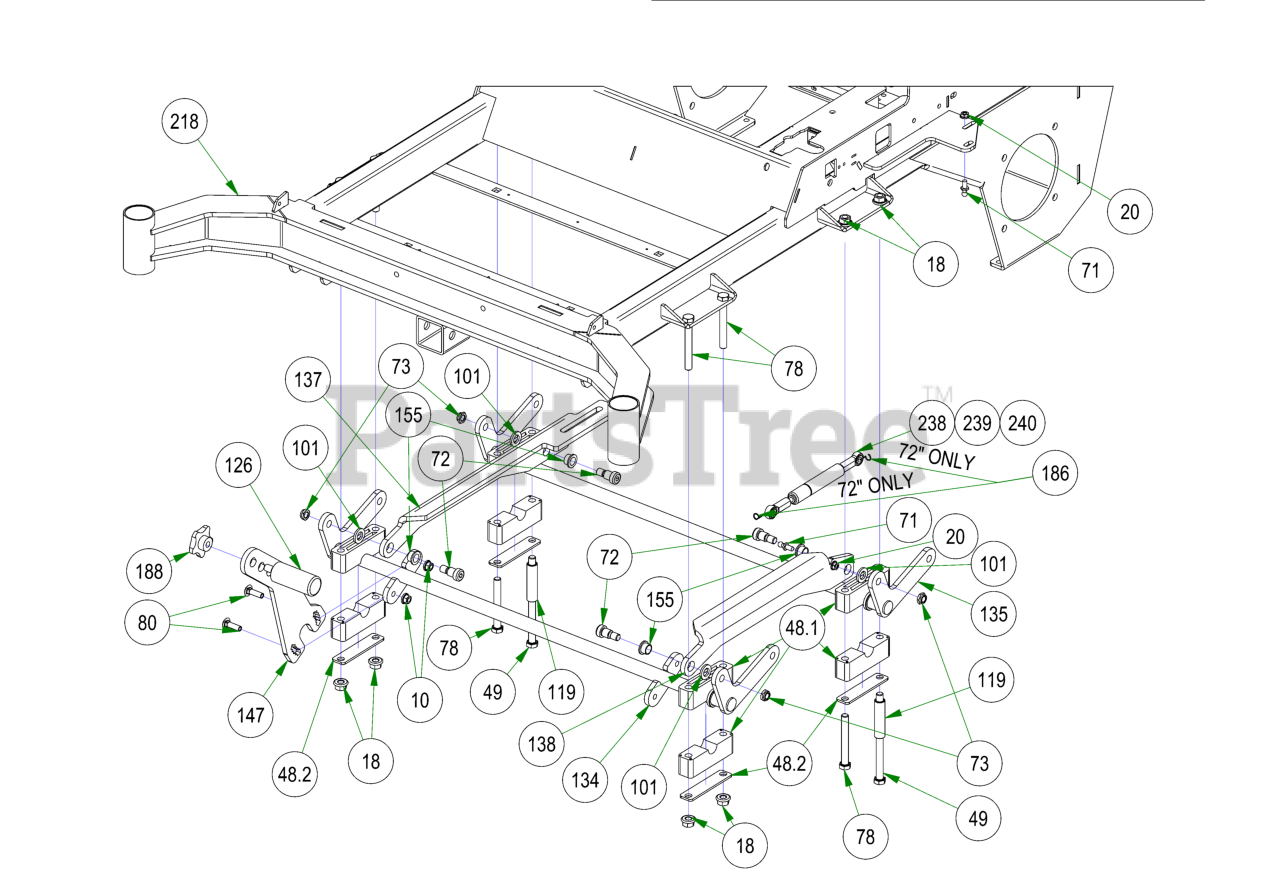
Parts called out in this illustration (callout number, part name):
5	.625 ID x 1.250 OD x .062 THK F/W Nylon
10	3/8-16 NYLON INSERT FLANGE LOCKNUT (GR.F) ZINC
11	1/2-13 HEX SERRATED FLANGE NUT HARD/ZINC
14	1/2-13 HEX NUT ZINC
18	1/2-13 NYLON INSERT FLANGE LOCKNUT ZINC
19	1/4-20 HEX SERRATED FLANGE NUT HARD/ZINC
20	5/16-18 HEX SERRATED FLANGE NUT HARD/ZINC
48	Pillow Block Assembly
48.1	Two Piece Pillow Block
48.2	Two Piece Pillow Block Strap
49	1/2-13 X 7 HEX CAP SCREW (GR.5) ZINC
54	2 1/2 x 1/2 Carriage Bolt
71	10mm Damper Ball Stud-XP Linkage
72	5/8 X 5/8 SOCKET SHOULDER BOLT ZINC YELLOW
73	1/2-13 NYLON INSERT JAM LOCKNUT ZINC
75	1/4-20 X 1-1/4 HEX CAP SCREW (GR.5) ZINC
78	1/2-13 X 4 HEX CAP SCREW (GR.8) ZINC YELLOW
80	3/8-16 X 1-1/4 CARRIAGE BOLT ZINC
96	.517 SQ WDTH ID X .937 OD X .060 THICK F/W PHOS/OIL
101	.635 ID X 1.120 OD X .140 THICK FLAT WASHER NYLON
110	.505 ID X 1.000 OD X .125 THICK FLAT WASHER NYLON
115	5/8" Split Collar
117	MZ Deck Idler Spacer
119	2019 Deck Stop Spacer
126	Knurled Pedal
132	Dial Rod Plunger
133	2019 Outlaw Gen2 Deck Height Dial Rod Assy
133.1	3/8-24 Nylon Insert jam locknut
133.2	3/8" Flat Washer
133.3	2019 Deck Height Cam
133.4	2019 Outlaw Gen2 Dial Rod
134	2019 Outlaw Actuator - Front
135	2019 Outlaw Actuator - Rear
137	2019 Actuator Linkage – Right – Black
138	2019 Actuator Linkage - Left - Black
147	Foot Lift Upright Lever
150	2019 Outlaw Deck Travel Lock
155	.627 ID X .753 OD X .500 LGTH X 1.000 FLG OD X .094 FLG THICK FLANGED BEARING OIL-IMPREG BRNZ
161	Brake Spring
185	Seat Bracket Pin
186	Security Ring - PC744
188	Foot Pedal Knob 1/2-13
215	Travel Lock Rubber Grip
218	2022 Rebel Frame
238	200 lb Gas Spring- 54" Deck outlaw
239	250lb Gas Spring - 61" Deck
240	300lb Gas Spring - 72" Deck
